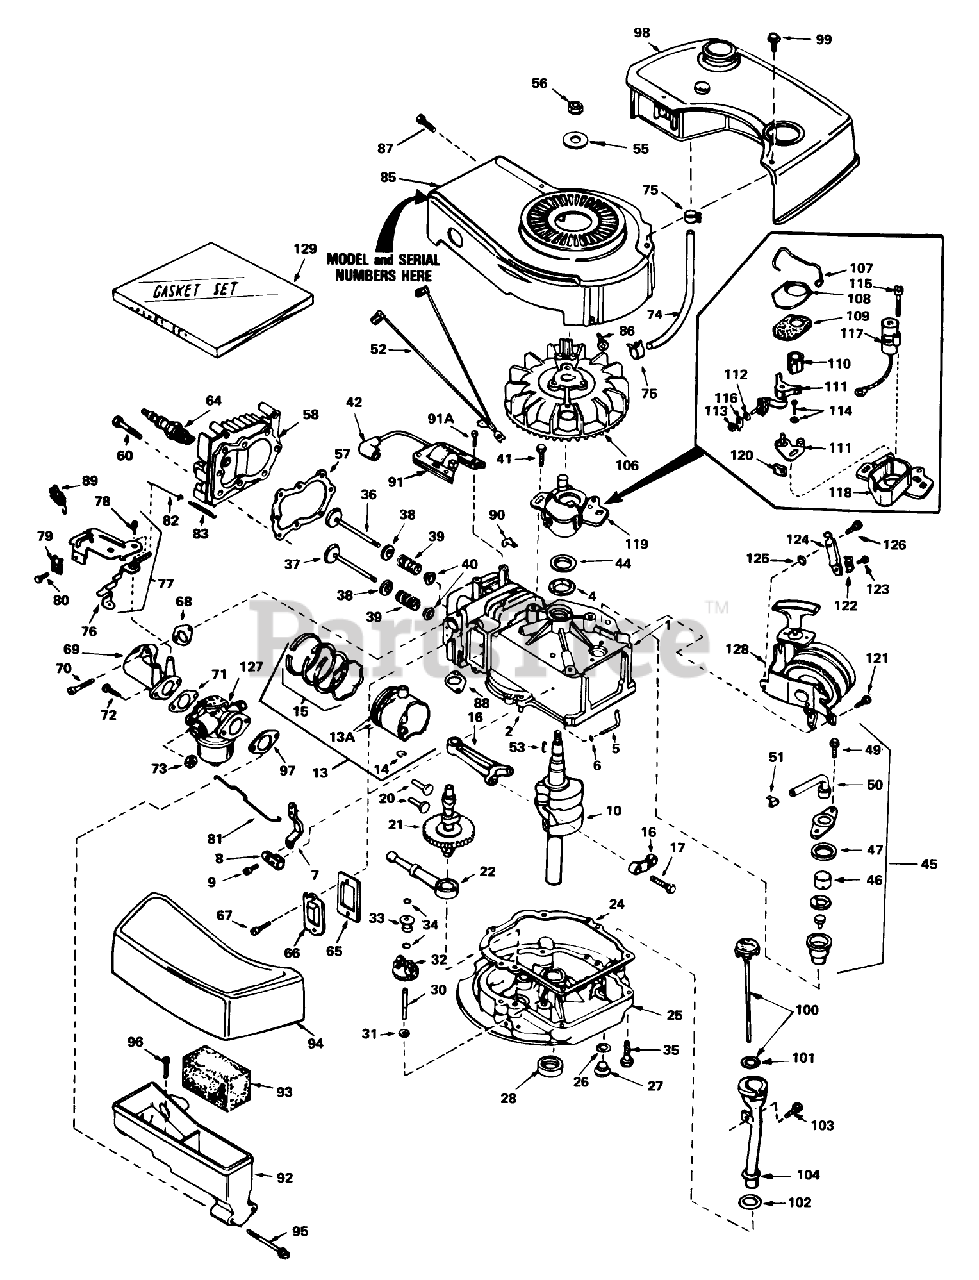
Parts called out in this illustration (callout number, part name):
1	Cyiinder Assy. (Incl. Ref. #2, 4 105)
2	Pin-Dowel
4	Seal-Oil
5	Rod, Governor (Incl. No. 36)
6	Washer-Flat
7	Governor Lever
8	Clamp-Lever, Governor
9	Screw
10	Crankshaft
13	Piston, Pin Ring Assy. (Std.)(Incl. Ref. #13A, 14 15)
13	Piston,Pin Ring Assy. (.010 over-size)(Incl. Ref. #13A, 14 15)
13	Piston, Pin Ring Assy. (Incl. Nos. 13A, 14 15)(.020 oversize)
13A	Piston Pin Assy. (Incl . Ref. . #14) (Std.)
13A	Piston Pin Assy. (Incl. Ref. #14) (.010 Oversize)
13A	Piston Pin Assy. (.020 oversize) (Incl. Ref. #14)
14	Ring-Retaining, Piston Pin
15	Ring Set Piston (Std.)
15	Ring Set Piston (.010 Oversize)
15	Ring Set Piston (.020 Oversize)
16	Rod Assy., Connecting (Incl. Ref. #17)
17	Bolt-Rod, Connecting
20	Lifter-Valve
21	Camshaft(Mech.Comp. Release)
22	Oil Pump ASM
24	Gasket, Mounting
25	Flange Assy., Mounting (Incl. Ref. #26thru 30)
26	Gasket-Oil Drain
27	Plug Oil Drain
28	Seal Oil
30	Shaft-Governor
31	Washer-Flat
32	Governor Gear ASM
33	Spool-Governor
34	Ring-Retaining
35	Screw (1/4-20 x 1-1/4)
36	Valve, Intake (Incl. Ref. #38, 39 40) (Std.)
36	Valve, Exhaust (1/32" Oversize) (Incl. Nos. 8, 9 10)
37	Valve, Exhaust (Standard) (Incl. Nos. 8, 9 10)
37	Valve, Exhaust (1/32" Oversize) (Incl. Nos. 8, 9 10)
38	Cap-Upper Valve Spring
39	Spring-Valve
40	Cap-Valve, Spring
41	Screw
42	Cover-Spark Plug
44	Gasket Stator
45	Breather Assy. (Incl. Ref. #46 thru 51)
46	Element-Breather
47	Gasket-Breather
49	Screw (10-24 x 9/16)
50	Tube, Breaker
51	Clip, Breather
52	Wire Ground
53	682488 LB GRASS HI-
55	Washer-Belleville
56	Nut-Flywheel
57	63573 GIL 42 SNWTHW
58	Head-Cylinder
60	Screw (5/16-18x1-1/2)
64	Plug, Spark (J17LM or equiv.)
64	Plug, Spark (Champion RCJ-8)
65	Gasket-Breather
66	Cover-Valve
67	Screw
68	Gasket-Intake
69	Pipe, Intake (Incl. No. 68)
70	Screw (1/4-20 x 1)
71	Gasket-Carburetor
73	Nut and Lock Washer (1/4-28)
74	Line-Fuel
75	Clamp-Line, Fuel
76	Lever Control
77	Control Assy., Speed (Incl. Nos, 76, 78 89)
78	Screw, Hex Washer Hd Shoulder Self-Tap
79	Conduit
80	Screw (10-32 x 3/8)
81	Link-Throttle
82	Link Governor Spring
83	Spring Governor
85	Housing Blower
86	Screw
87	Screw (10-24 x 9/16)
88	Gasket Exhaust
89	Terminal
90	Clip-Wire
91	Lamination Coil Assy. (Incl. No. 42)
91A	Screw
92	Body Air Cleaner
93	Filer, Air
94	Cove, Air Cleaner
95	Screw Fil Hd.
96	Screw, Hex Hd.
97	Gasket-Air Cleaner
98	Tank, Fuel
99	Screw (10-32 x 35/64)
100	Dipstick, Oil (Incl. Ref. #101)(Twist Lock)
101	O-Ring
102	Gasket
103	Screw (10-32 x 1/2)
104	Tube-Oil Fill
106	FIywheel
107	Spring Breaker Box
108	Cover-Dust
109	Gasket-Dust Cover
110	Cam-Breaker
111	Breaker Assy.
112	Washer
113	DECAL
114	Breaker Screw
115	Condenser Screw
116	Terminal, Ground
117	Condenser
118	Stator Plate
119	Stator Plate Assy. (incl. Nos. 107, 111 thru 118 120)
120	Felt,Cam Wiper
121	Screw (1/4-20 x 1/2)
122	Conduit
123	Screw (10-32 x 3/8)
124	Bracker
125	Washer
126	Screw (1/4-20 X 5/8)
127	Carburetor (Incl. Ref. #71 )
128	Starter
129	Gasket Set
